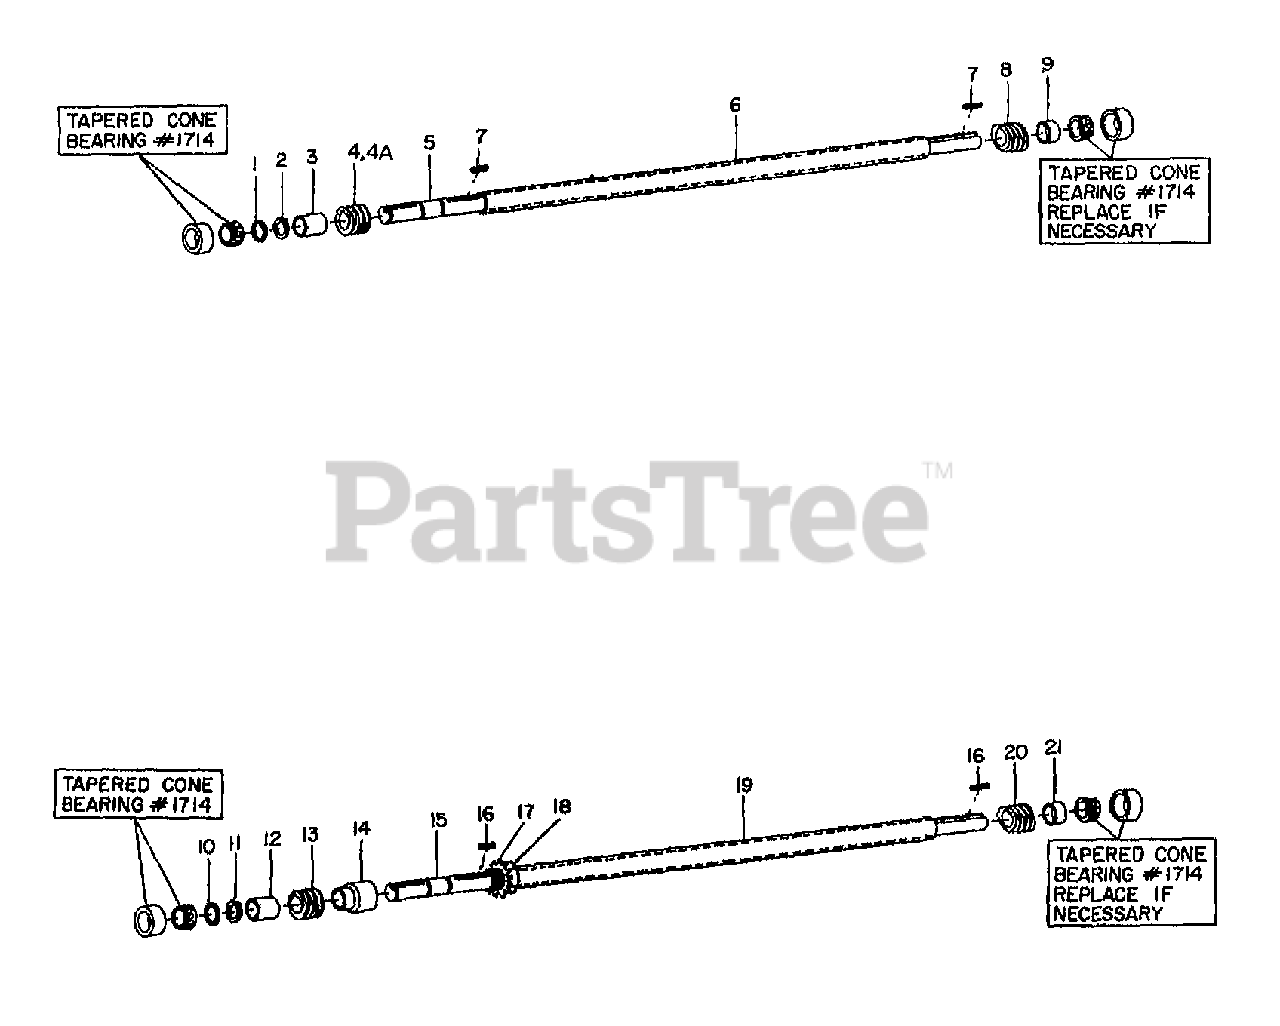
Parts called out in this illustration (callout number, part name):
1	SHIM-1.0X.7656X.062
2	RING-RETAIN EXT .707 ID
3	SPACER-1X.76X1.25
4	WORM-1.25 PD .26 LEAD
4A	GEAR-WORM 1.25 PD .62 LEAD
5	DRIVESHAFT-MACH
6	SLEEVE-WORM SPACER
7	KEY-.188 SQX1.0
8	WORM-1.25 PD .62 LEAD
9	SPACER-1X.76X.54
10	SHIM-1.0X.7656X.062
11	RING-RETAIN EXT .707 ID
12	SPACER-1X.76X1.25
13	GEAR-WORM 1.25 PD .62 LEAD
14	SPACER-1.25X(VAR)X1.5
15	DRIVESHAFT-MACH
16	KEY-.188 SQX1.0
17	SPACER SLEEVE
18	NUT 1.0-14 ADJ
19	TUBING-MACH
20	WORM-1.25 PD .62 LEAD
21	SPACER-1X.76X.54
